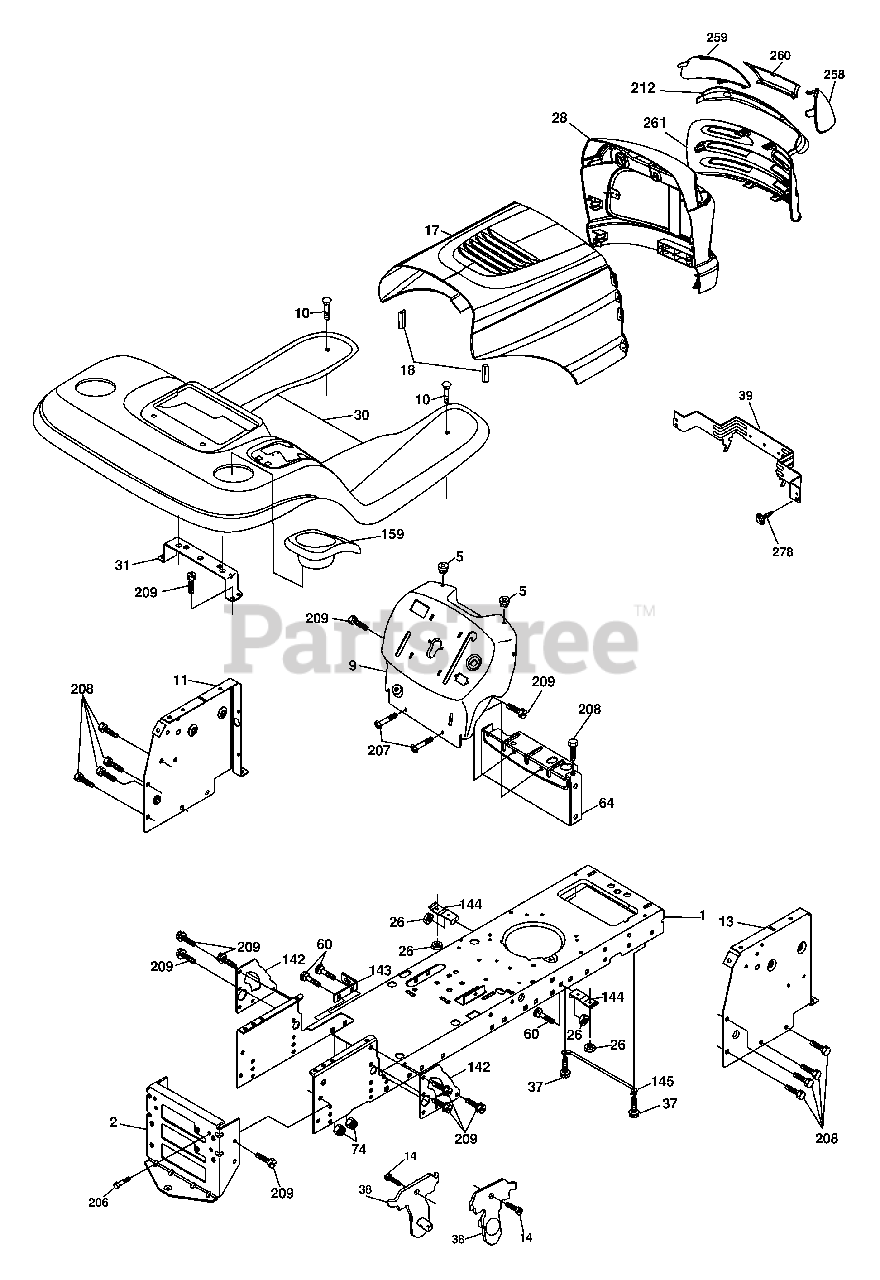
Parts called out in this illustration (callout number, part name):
1	Chassis
5	Bumper Hood/Dash
9	Dash
10	Bolt Carriage 3/8-16 x 1
11	Panel Dash Lh
13	Panel Dash Rh
14	Screw Thdrol 3/8-16 x 1/2
17	Hood
18	Bumper Hood 1.75
26	Nut Lock Hex W/Ins 3/8-16 unc
28	Grille/Lens Asm.
30	Fender Footrest
31	Bracket Fender
37	Screw Thdrol 6/16-18 x 1/2 TYT
38	Bracket Asm Pivot Mower Rear
39	Bracket Pivot Hood
60	Bolt RDHD Sqnk 3/8-16 unc x 3/4
64	Dash Lower STLT
74	Nut Crownlock 3/8-16 unc
142	Plate Reinforcement STLT
143	Bracket Swaybar Chassis
144	Bracket Footrest Step-thru
145	Rod Pivot Chassis/Hood
159	Cupholder
206	Bolt Shoulder 5/16-18
207	Screw 5/16-18 x 1/2
208	Screw Thdrl 3/8-16 x 1/2
209	Screw Hexwsh Thdr 3/8-16 x 3/4
212	Insert Lens
258	Lens RH
259	Lens LH
260	Cover Lens
261	Insert Grille
278	Screw 10 x 3/4 Single Lead-Hex
